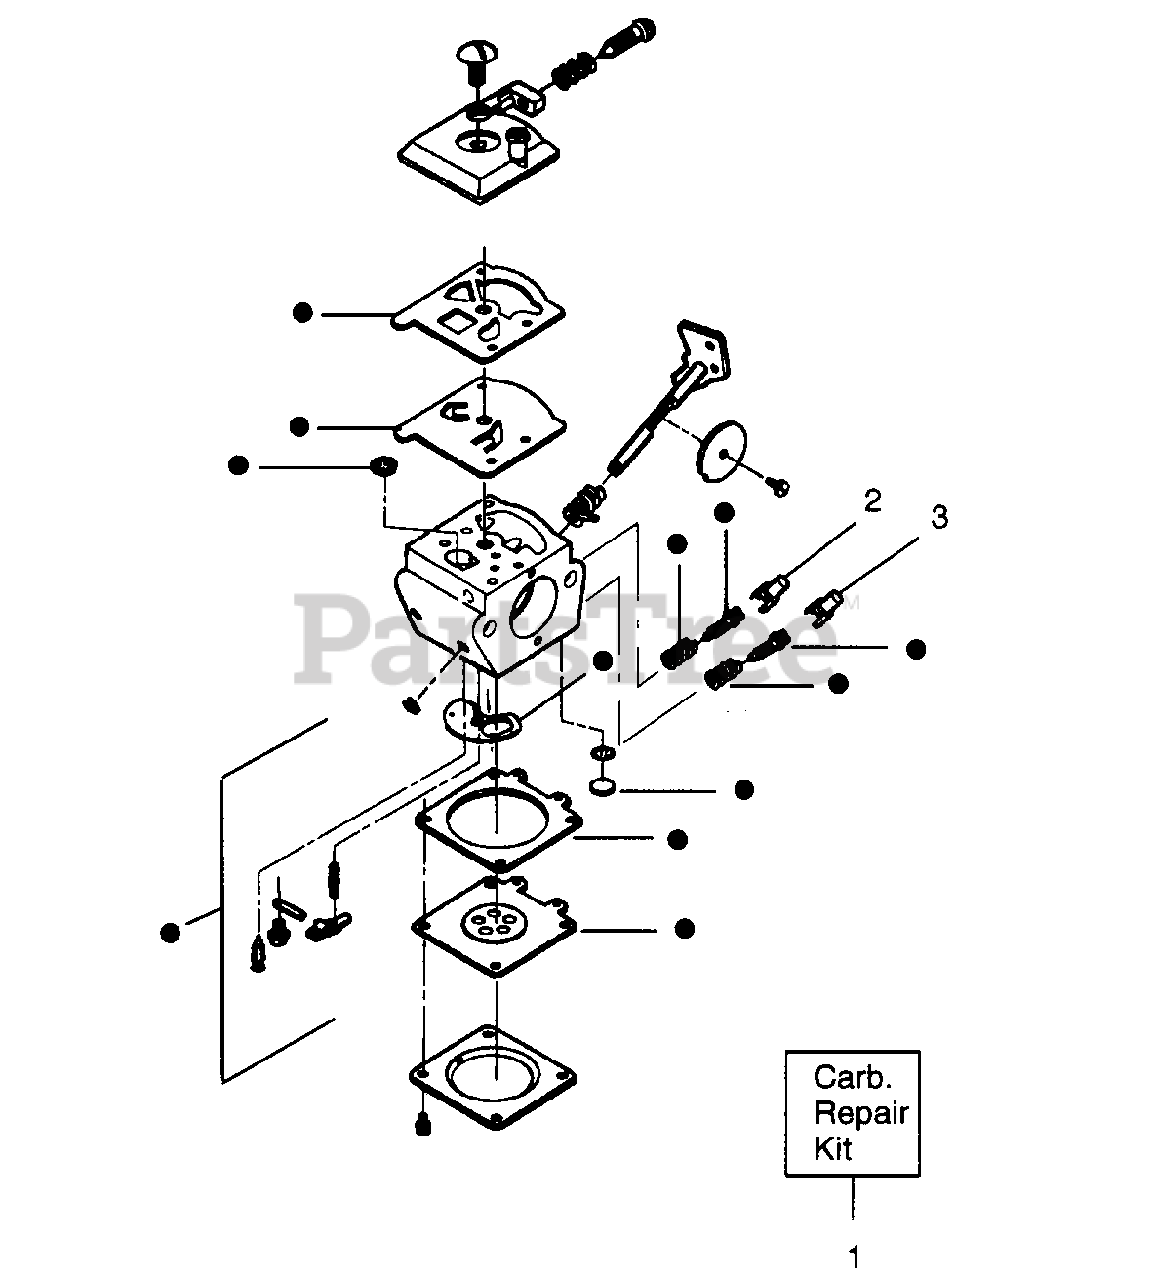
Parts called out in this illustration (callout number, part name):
1	Carburetor Repair Kit (DOT Indicates Contents on illus.)
2	Limiter Cap-Low
3	Limiter Cap-High
